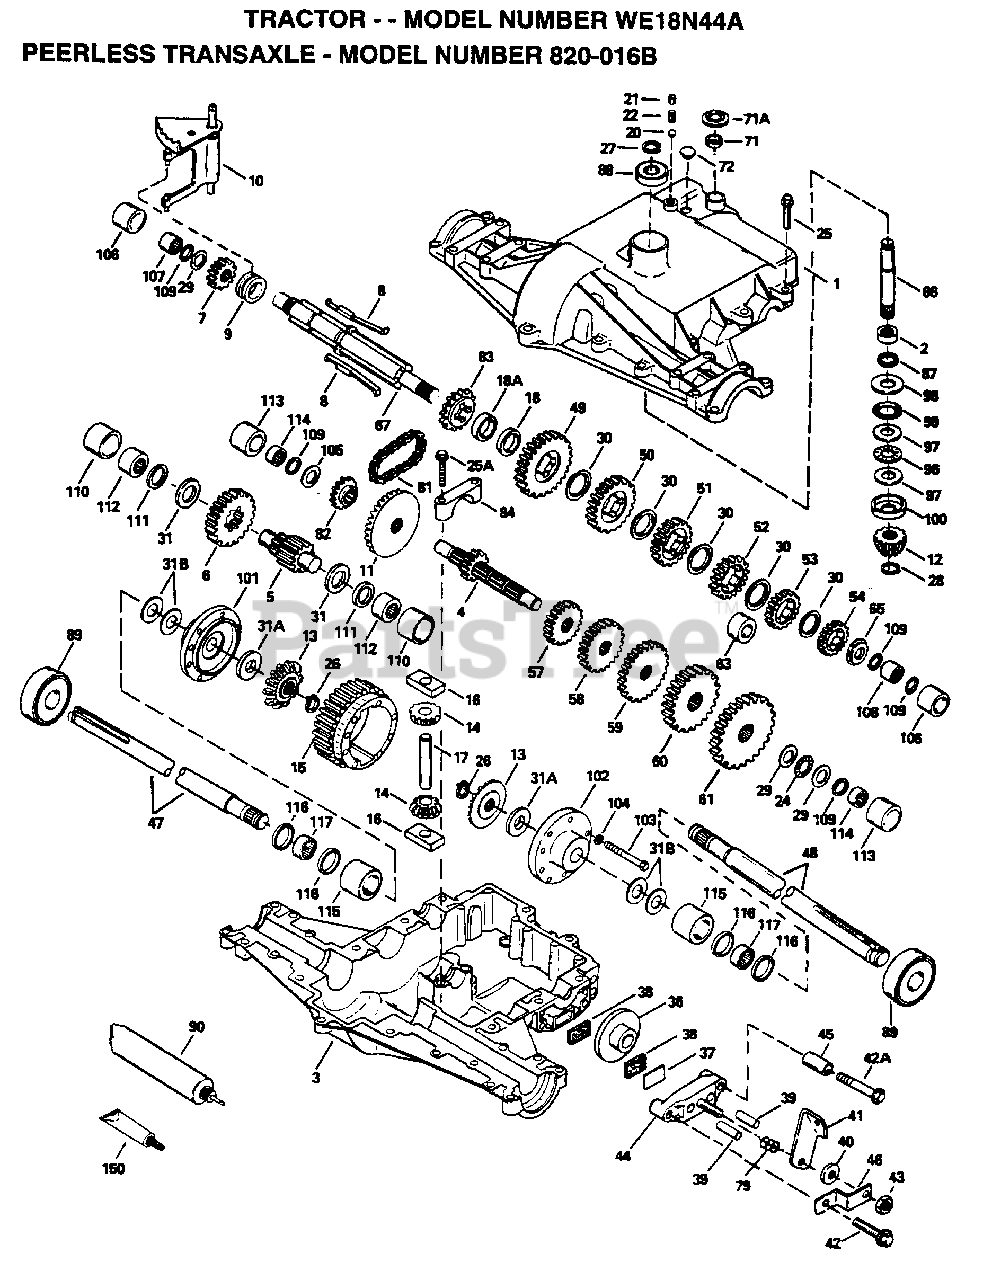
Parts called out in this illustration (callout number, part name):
1	COVER TRANSAXLE
2	BEARING NEEDLE
3	CASE TRANSAXLE
4	SHAFT COUNTER
5	SHAFT, OUTPUT, 9T
6	GEAR, OUTPUT, 35T
7	GEAR, SPUR, 15T
9	COLLAR SHIFT
10	ROD AND FORK ASSY SHIFT
11	GEAR BEVEL, 33T
12	BEVEL PINION, 13T
14	PINION, 10T
15	GEAR, RING, 31T
16	BLOCK DRIVE
18	SPACER, .350/.340 THICK
18A	SPACER, .276/.268 THICK
20	BALL STEEL, 5/16" DIA.
21	SCREW, 3/8-16 X 3/8"
24	THRUST BEARING
25	SCREW HEX HD 5/16-18 X 1-1/4
25A	SCREW, 1/4-20 X 1-1/4
28	RETAINING RING
29	WASHER THRUST
30	WASHER THRUST
31	WASHER THRUST
31B	WASHER THRUST
37	PLATE BRAKE PAD
41	LEVER BRAKE
42	SCREW, 1/4-20 X 1-1/4
42A	SCREW, 1/4-20 X 2-1/4
43	LOCKNUT 5/16-24
44	HOLDER BRAKE PAD
46	BRKT BRAKE LEVER
47	AXLE, 12-5/16" LONG
48	AXLE, 16-3/16" LONG
49	GEAR, SPUR, 41T
50	GEAR, SPUR, 35T
51	GEAR, SPUR, 30T
52	GEAR, SPUR, 25T
53	GEAR, SPUR, 22T
54	GEAR, SPUR, 19T
57	GEAR, SPUR, 15T
58	GEAR, SPUR, 20T
59	GEAR, SPUR, 25T
60	GEAR, SPUR, 28T
61	GEAR, SPUR, 31T
67	SHAFT BRAKE
71	SEAL SQUARE CUT
72	PLUG, THRDED, 9/16-18
81	CHAIN, ROLLER
82	SPROCKET 9T
83	SPROCKET 18T (REV)
84	BEARING CAP
87	OIL SEAL 3/4
88	BEARING BALL
89	BEARING BALL
90	GREASE BENTONITE, 32 OZ.
96	BEARING THRUST
97	WASHER THRUST
99	SHAFT INPUT
100	WASHER CUPPED
101	CARRIER DIFF THREADED HOLES
102	CARRIER DIFF
103	SCREW, 1/4-20 X 2-1/4
104	WASHER LOCK 1/4
107	BEARING NEEDLE
108	BEARING NEEDLE
110	SLEEVE STEPPED
111	RING SQ CUT
112	BEARING NEEDLE CAPPED
113	SLEEVE STEPPED
114	BEARING NEEDLE CAPPED
115	SLEEVE STEPPED
116	RING SQ CUT
117	BEARING NEEDLE
150	GASKET ELIMINATOR
